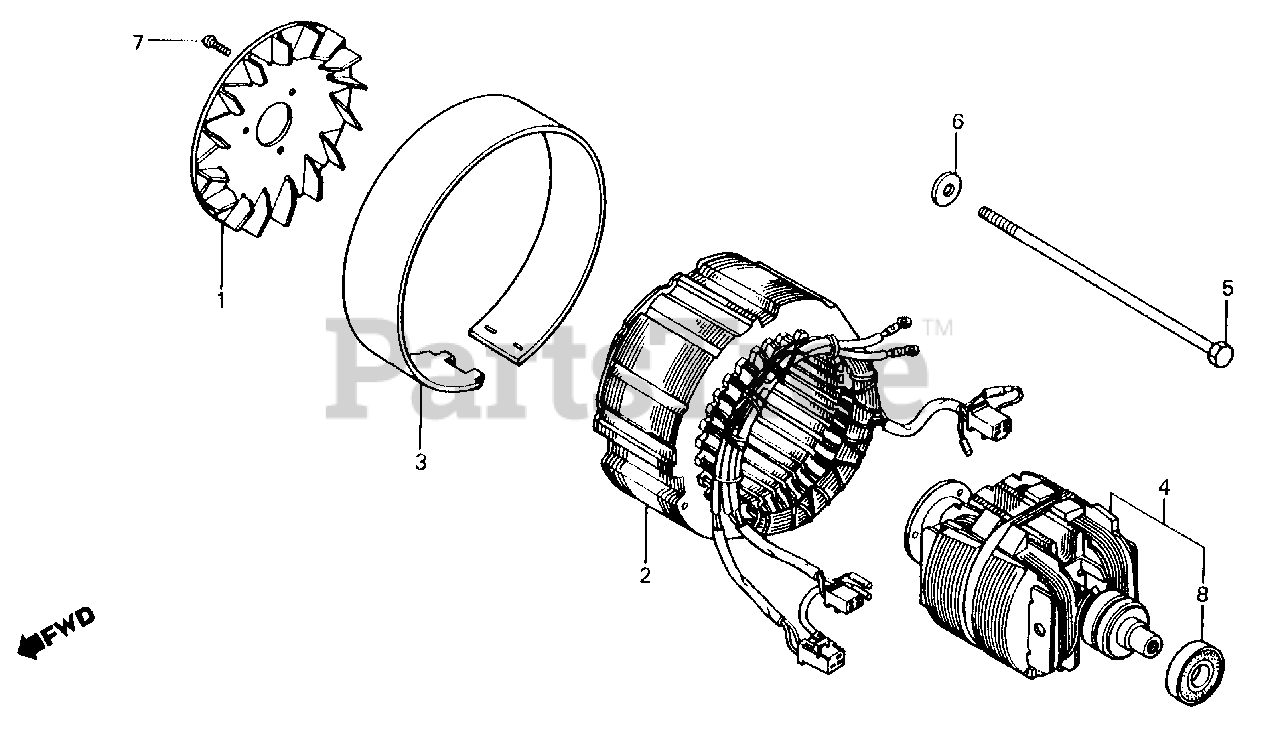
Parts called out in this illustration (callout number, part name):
2	STATOR ASSY.
3	COVER, STATOR *R8* (BRIGHT RED)
4	ROTOR
5	BOLT, HEX. (10X204) (NOT AVAILABLE)
6	WASHER, PLAIN (10MM)
7	SCREW, TAPPING (5X14)
7	SCREW, PAN (5X10)
8	BEARING, RADIAL BALL (6304UU)
